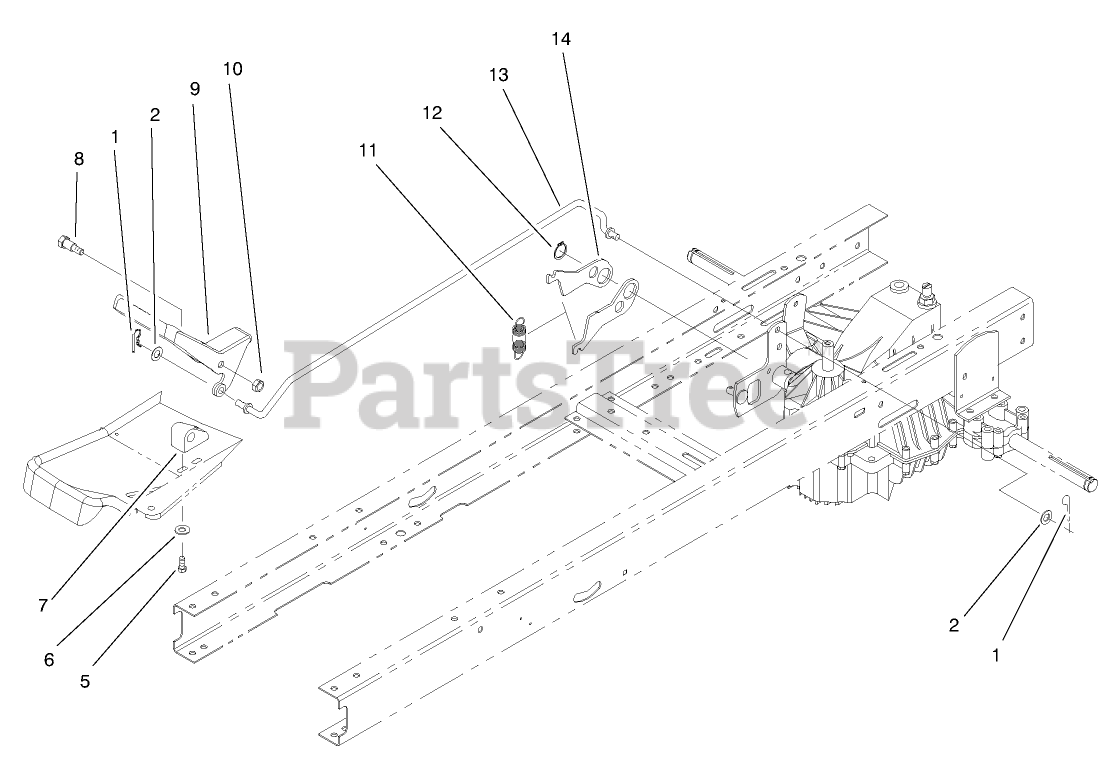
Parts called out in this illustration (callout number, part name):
2	WASHER-PLAIN
5	SCREW-PLASTITE
6	WASHER-FLAT
7	BLOCK-PIVOT
8	SCREW-SHOULDER, HH
9	PEDAL SPEED CONTROL
11	SPRING-EXTENSION
12	RING-SNAP
13	SPEED CONTROL ROD
14	NEUTRAL RETURN LEVER
